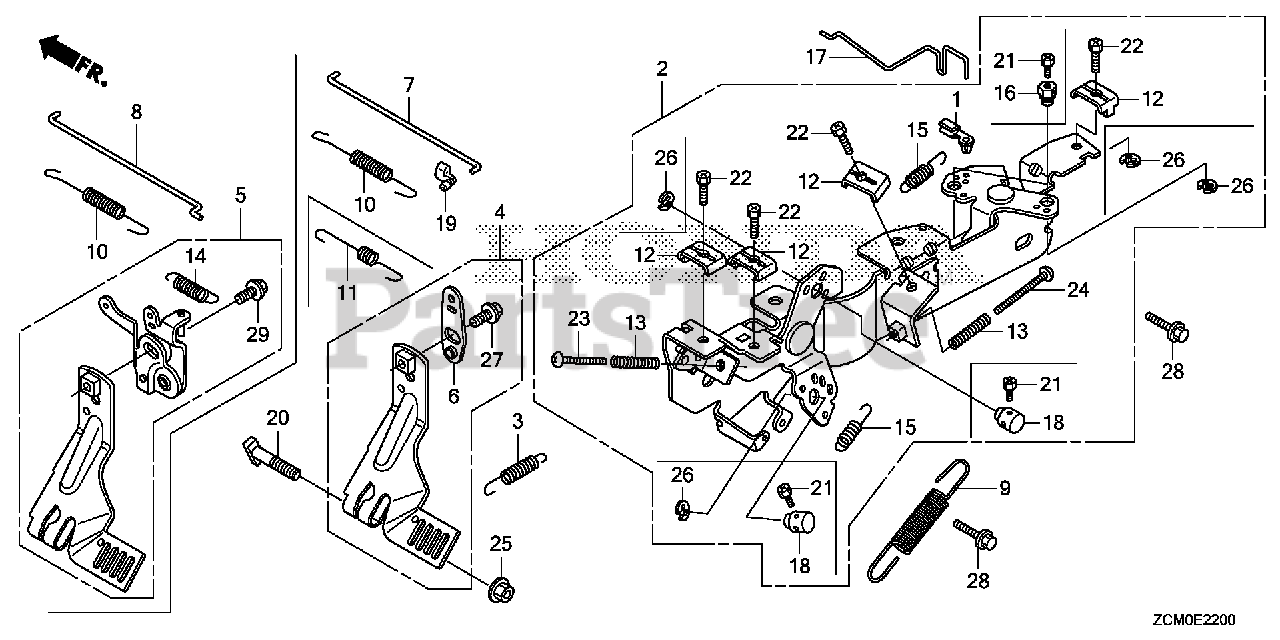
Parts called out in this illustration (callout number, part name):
1	JOINT, ROD
2	CONTROL ASSY.
3	SPRING, STARTER
4	ARM, GOVERNOR
6	ARM, SUB
7	ROD, GOVERNOR
9	SPRING, GOVERNOR
10	SPRING, THROTTLE RETURN
12	HOLDER, CABLE
13	SPRING, CONTROL ADJUSTING
15	SPRING, CABLE RETURN
16	HOLDER, WIRE
17	ROD, CHOKE CONTROL
18	HOLDER, CABLE
19	BUSH, LINKAGE
20	BOLT, GOVERNOR ARM
21	BOLT, RECESSED (4X6)
22	BOLT, RECESSED (5X16)
23	SCREW, PAN (5X30)
24	SCREW, PAN (5X45)
25	NUT, FLANGE (6MM)
26	E-RING (5MM)
27	BOLT, FLANGE (6X10)
28	BOLT, FLANGE (6X14)
